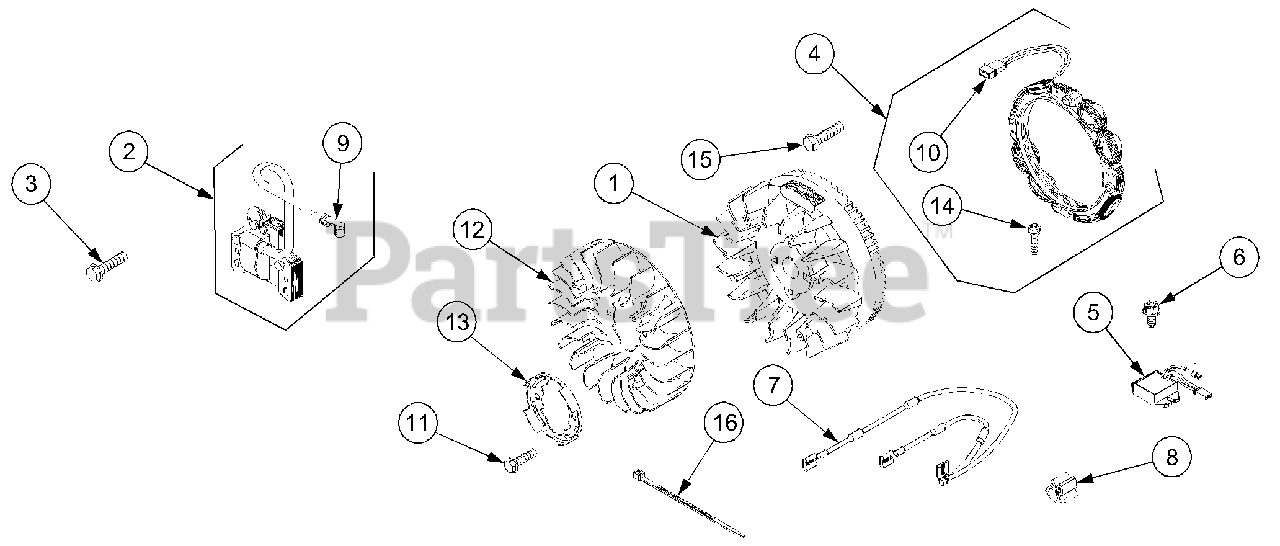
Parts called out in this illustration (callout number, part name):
1	Flywheel & Ring Gear
2	Armature, Magneto
3	Screw, Magneto Armature
4	Alternator
5	Regulator
6	Screw, Regulator
7	Wire Assembly
9	Termainl, Spark Plug
10	Wire/Connector, Alternator
11	Screw, Fan Retainer
12	Fan, Flywheel
13	Retainer, Fan
14	Kit, Screw/Washer
15	Screw, Alternator
16	Tie, Cable
